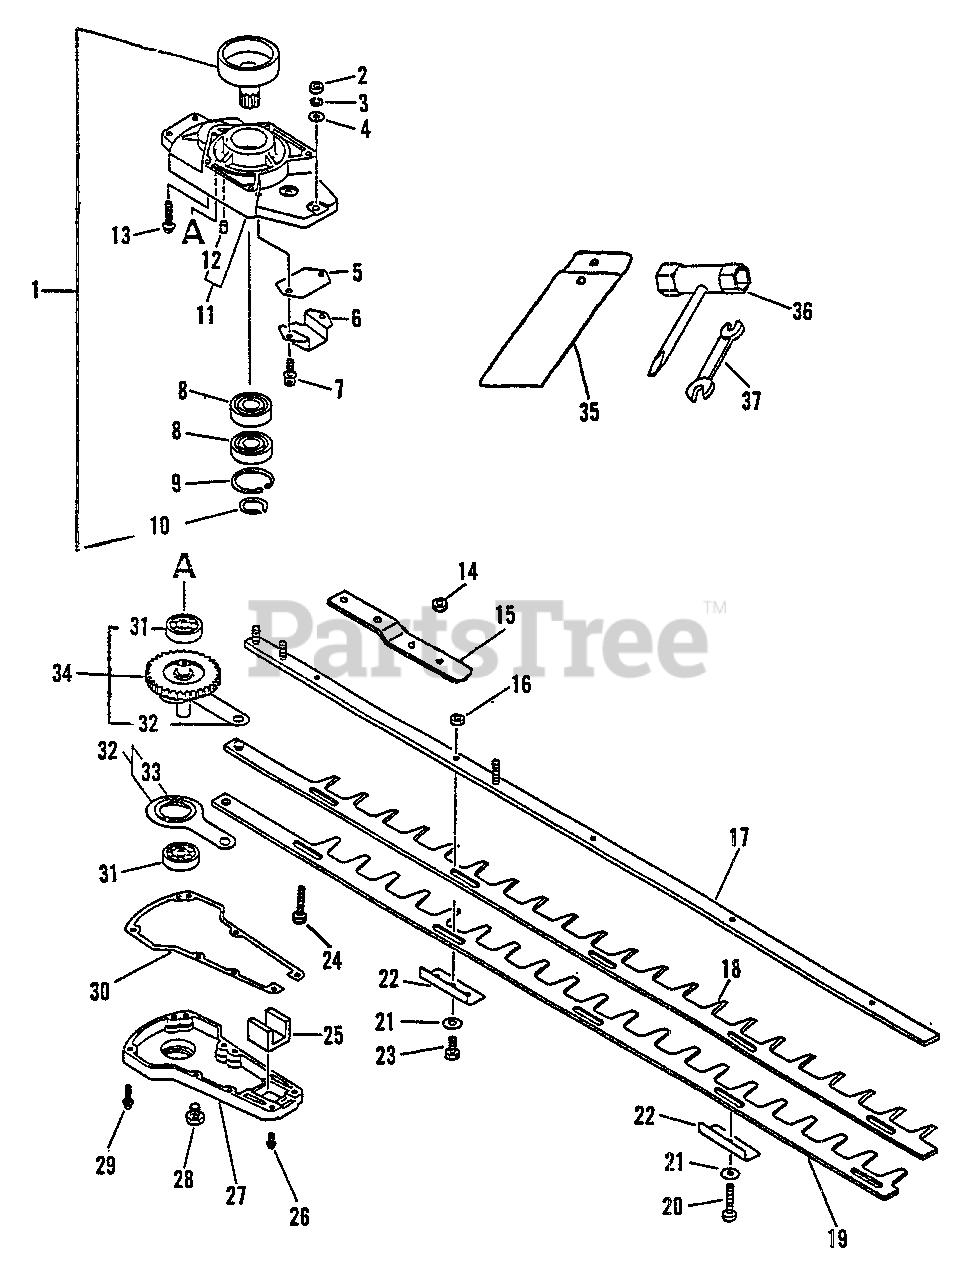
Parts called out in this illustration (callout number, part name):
1	DRUM, CLUTCH
2	NUT, HEX M6
3	WASHER, SPRING 6
4	WASHER 6.5×11.5×0.8
5	GUIDE
6	GUIDE
7	BOLT 5×14
8	BEARING, BALL 6003
9	RING, SNAP 35
10	RING, RETAINING - 16
11	CASE, GEAR
12	PIN, LOCATING 4
13	BOLT 5×30
15	BRACKET, BLADE
16	NUT, LOCK 6
17	BAR, FRAME
18	BLADE - UPPER
19	BLADE - LOWER
20	BOLT 6×22
22	INSULATOR
23	BOLT 6×40
24	BOLT 6×25
26	SCREW 4×14
27	LID, GEAR CASE
28	BOLT 8×8 SP
29	SCREW 4×22
30	GASKET, GEAR CASE
31	BEARING, BALL 6200
32	CONNECTING ROD ASSY
33	BEARING, NEEDLE
34	GEAR ASSY
35	BAG, TOOL
36	WRENCH 14×19 W/S.DRIVER
37	SPANNER 8×10
